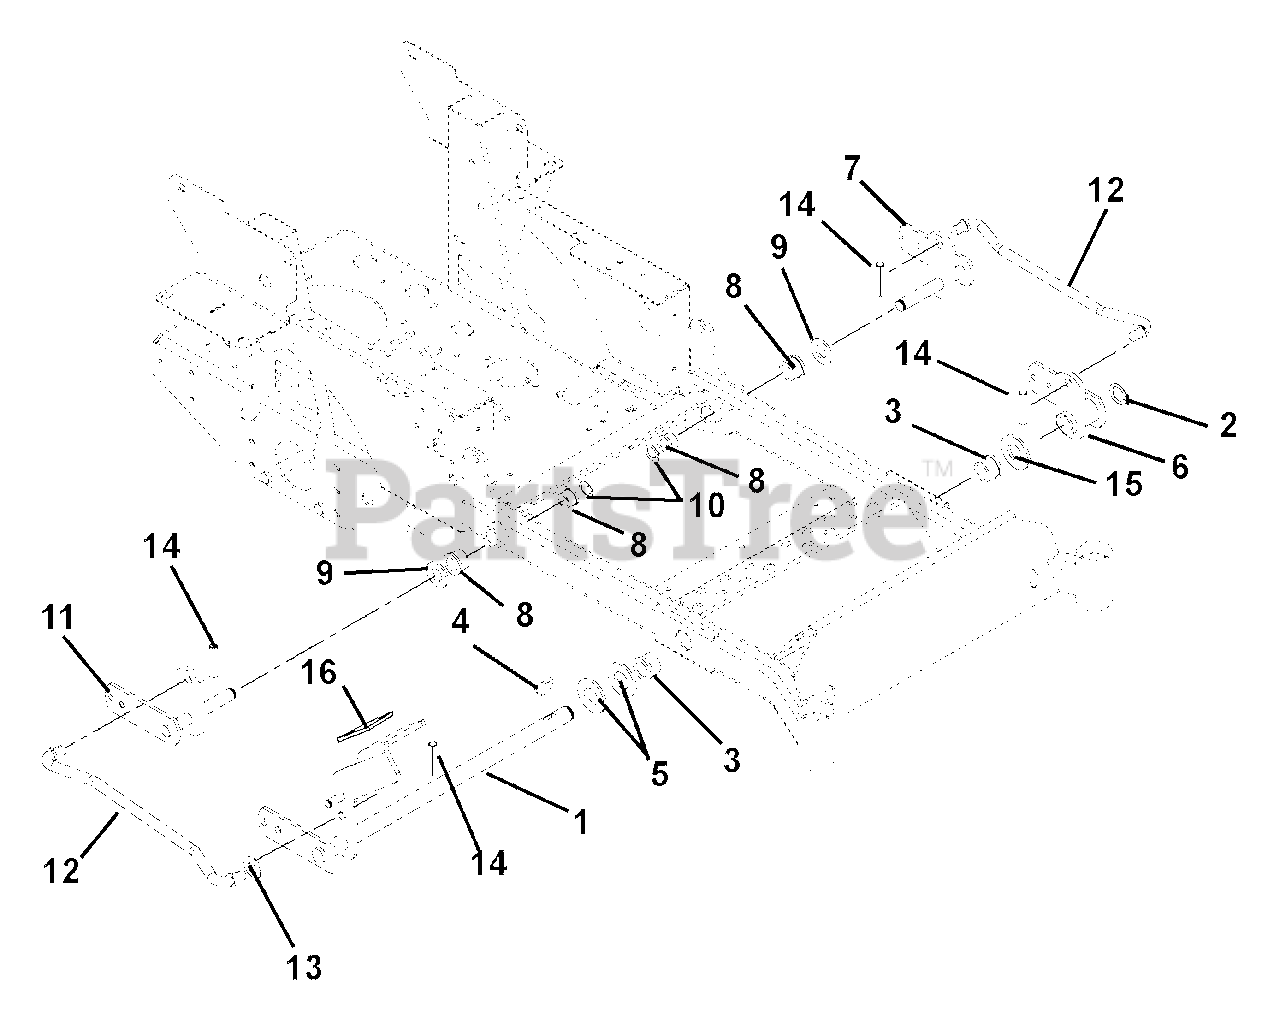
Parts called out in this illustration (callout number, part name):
1	WMT, FRONT MOWER LIFT
2	RG-RTNG-EXT 1.00X.078
3	BSHG-FLG1.020X1.385X.75X1.75NY
4	KEY-WDRF .25X1.00 HRD #15
5	WSHR-FL-STL- 1.062X2.0X.134 YZ
6	WMT, FRONT MOWER LIFT-LH
7	WMT, REAR LIFT ARM -LH
8	BSHG-FLG .762X1.0X.580X1.48 NY
9	WSHR-HDND-THRST .758X1.23X.031
10	RG-RTNG-EXT .689X.078
11	WMT, REAR LIFT ARM - RH
12	ROD, LIFT ASSIST 16.35"
13	@WSHR-FL-STL.656X1.31X.095 YWZ
14	PIN-ROLL .250X1.25 STNLESS STL
15	WSHR-HDND-THRUST 1.00X1.55X.03
16	GRIP, PEDAL 1.50 X 3.00
